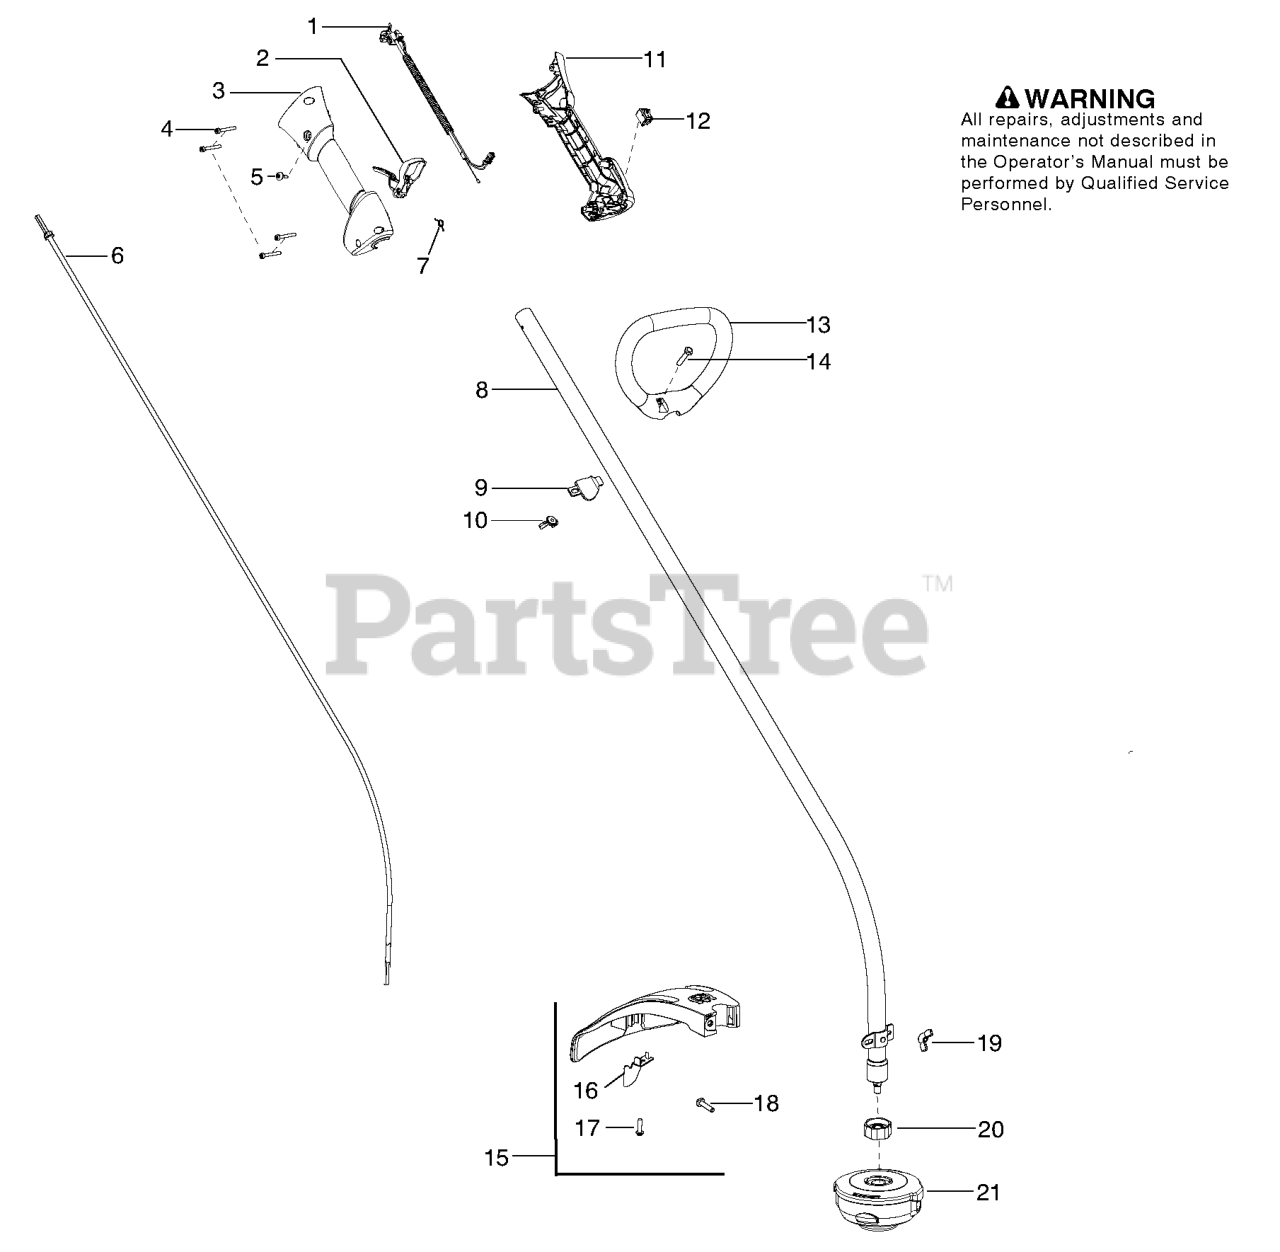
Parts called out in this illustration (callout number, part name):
1	Assy-Cable/Wire Harness
2	Trigger
3	Housing-Throttle (RH)
4	Screw
5	Screw
6	FLEX SHAFT 52"
7	SPRING TRIGGER
8	KIT DRIVESHAFT
9	CLAMP ASSIST HANDLE
10	WINGNUT, TYPE 2
11	Housing-Throttle (LH)
12	Kit-Switch
14	BOLT, TYPE 2
15	TRIMMER GUARD 128C
16	KIT - LIMITER - LINE
18	BOLT, TYPE 2
19	WINGNUT, TYPE 2
21	T25 TRIM HEAD RH
